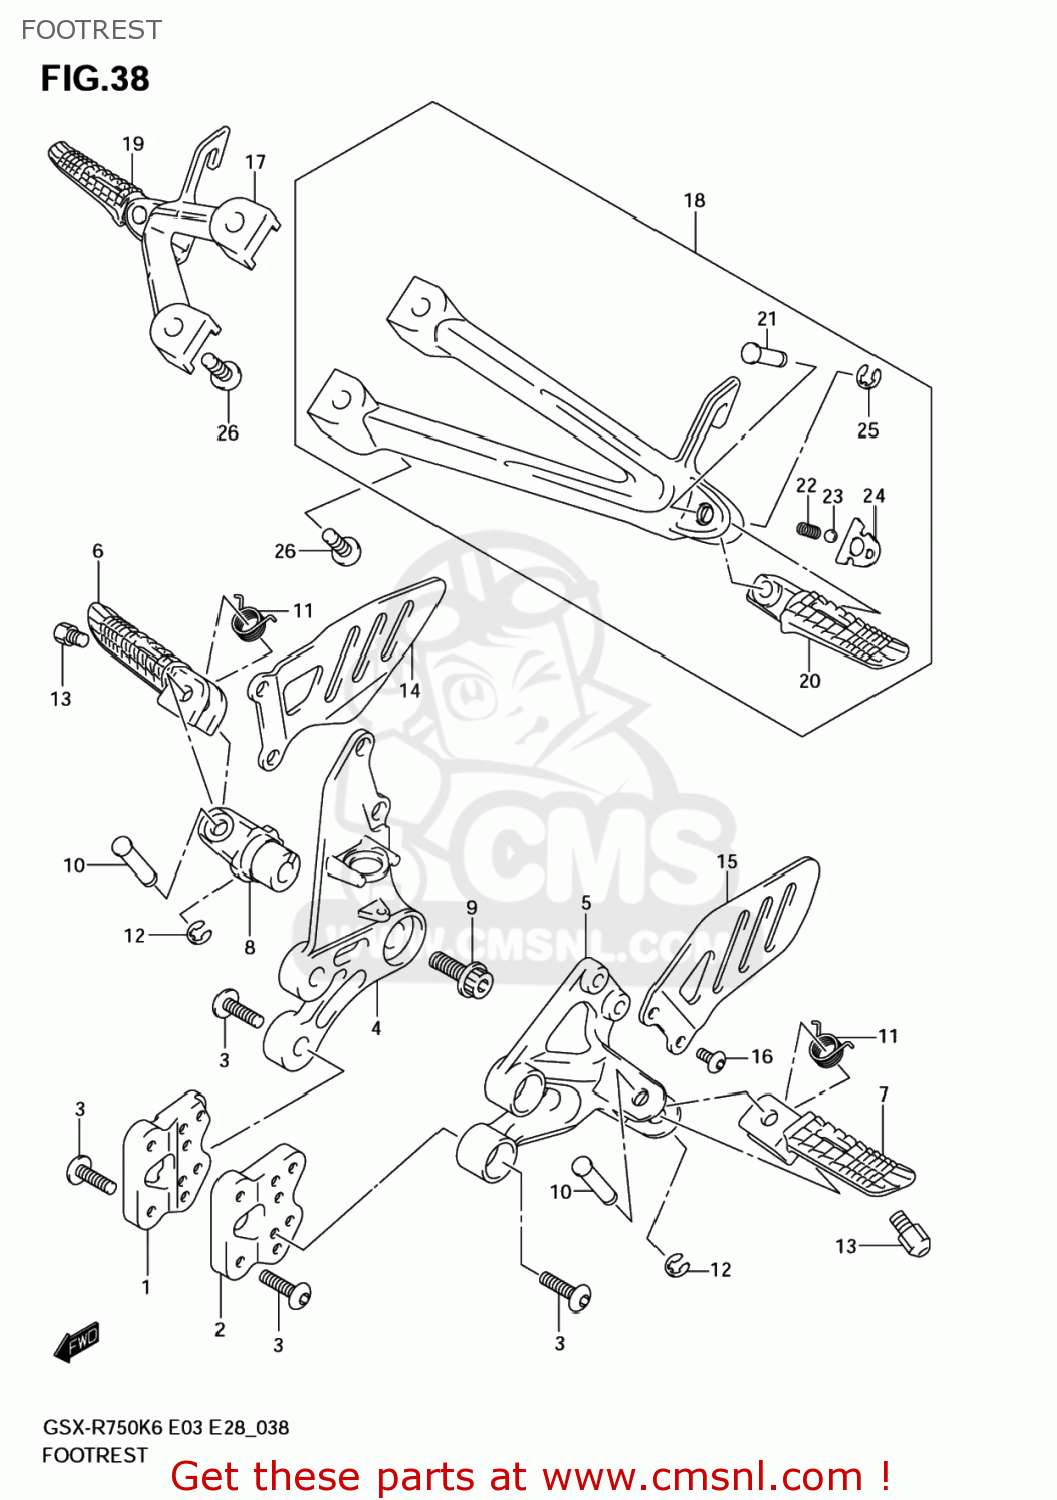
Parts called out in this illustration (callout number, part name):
1	BRACKET,FR FOOTREST NO.1,R
2	BRACKET,FR NO.1,L
3	BOLT(8X23)
4	BRACKET,FR NO.2,R
5	BRACKET,FR FOOTREST NO.2,L
6	BAR,FR FOOTREST,R
7	BAR,FR FOOTREST,L
8	HOLDER,FOOTRES
9	BOLT (10X28)
10	PIN
11	SPRING,FRONT F
12	E RING
13	BOLT,BANK SENS
14	GUARD,FR FOOTR
15	GUARD,FRONT FO
16	SCREW,FOOTREST GUARD,L
17	FOOTREST ASSY,
18	FOOTREST ASSY,
19	BAR,PILLION FOOTREST,R
20	BAR,PILLION FOOTREST,L
21	PIN
22	SPRING
23	BALL
24	PLATE,PILLION
25	E RING
26	BOLT(8X23)
